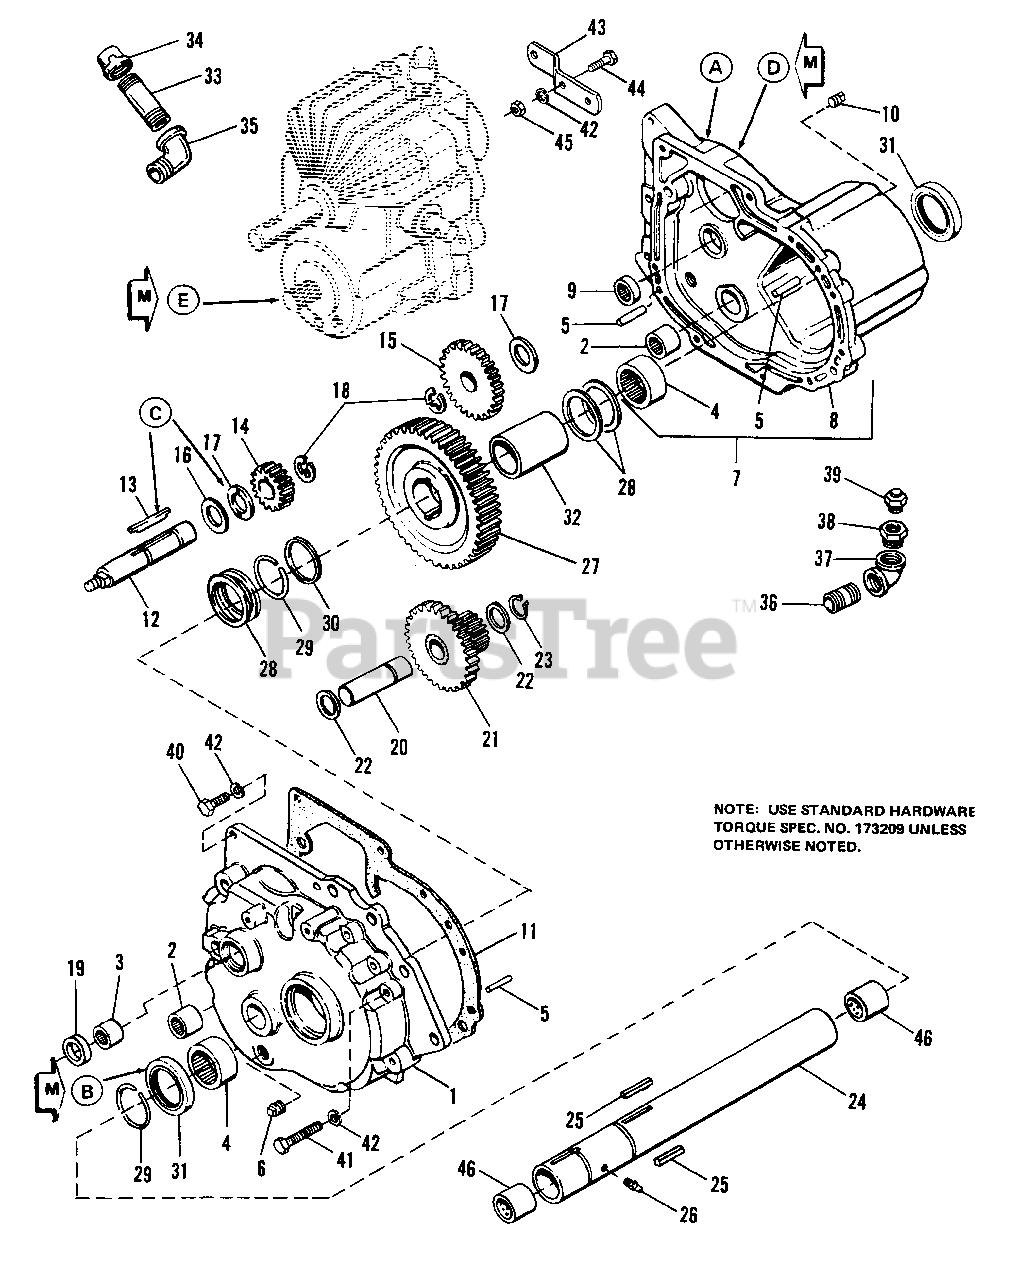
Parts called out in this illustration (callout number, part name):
1	COVER ASSY, Gear Case (w/bearings)
2	BEARING, Needle
3	BEARING, Needle
4	BEARING, Needle
5	PIN, Roll, 3/8 x 1
6	PLUG, Pipe
7	GEAR CASE ASSY (w/bearings)
9	BEARING, Needle
12	SHAFT, Brake
18	RING, Retaining
20	SHAFT, Interm.
21	PINION & SHAFT ASSY
23	RING, Retaining
24	AXLE TUBE ASSY
26	FITTING, Grease
27	GEAR, Drive
29	RING, Retaining
32	SPACER, L.H. Axle
33	NIPPLE, Pipe
34	CAP, Pipe
35	STREET, Elbow
36	NIPPLE, Pipe
37	ELBOW, Pipe
38	BUSHING, Pipe
39	VALVE, Relief
40	CAPSCREW, Hex Hd., 5/16-18 x 3/4
41	CAPSCREW, Hex Hd., 5/16-18 x 2
42	LOCKWASHER, 5/16
43	SUPPORT, Spring
44	CAPSCREW, Hex Hd., 5/16-18 x 1
45	NUT, Hex, Full, 5/16-18
